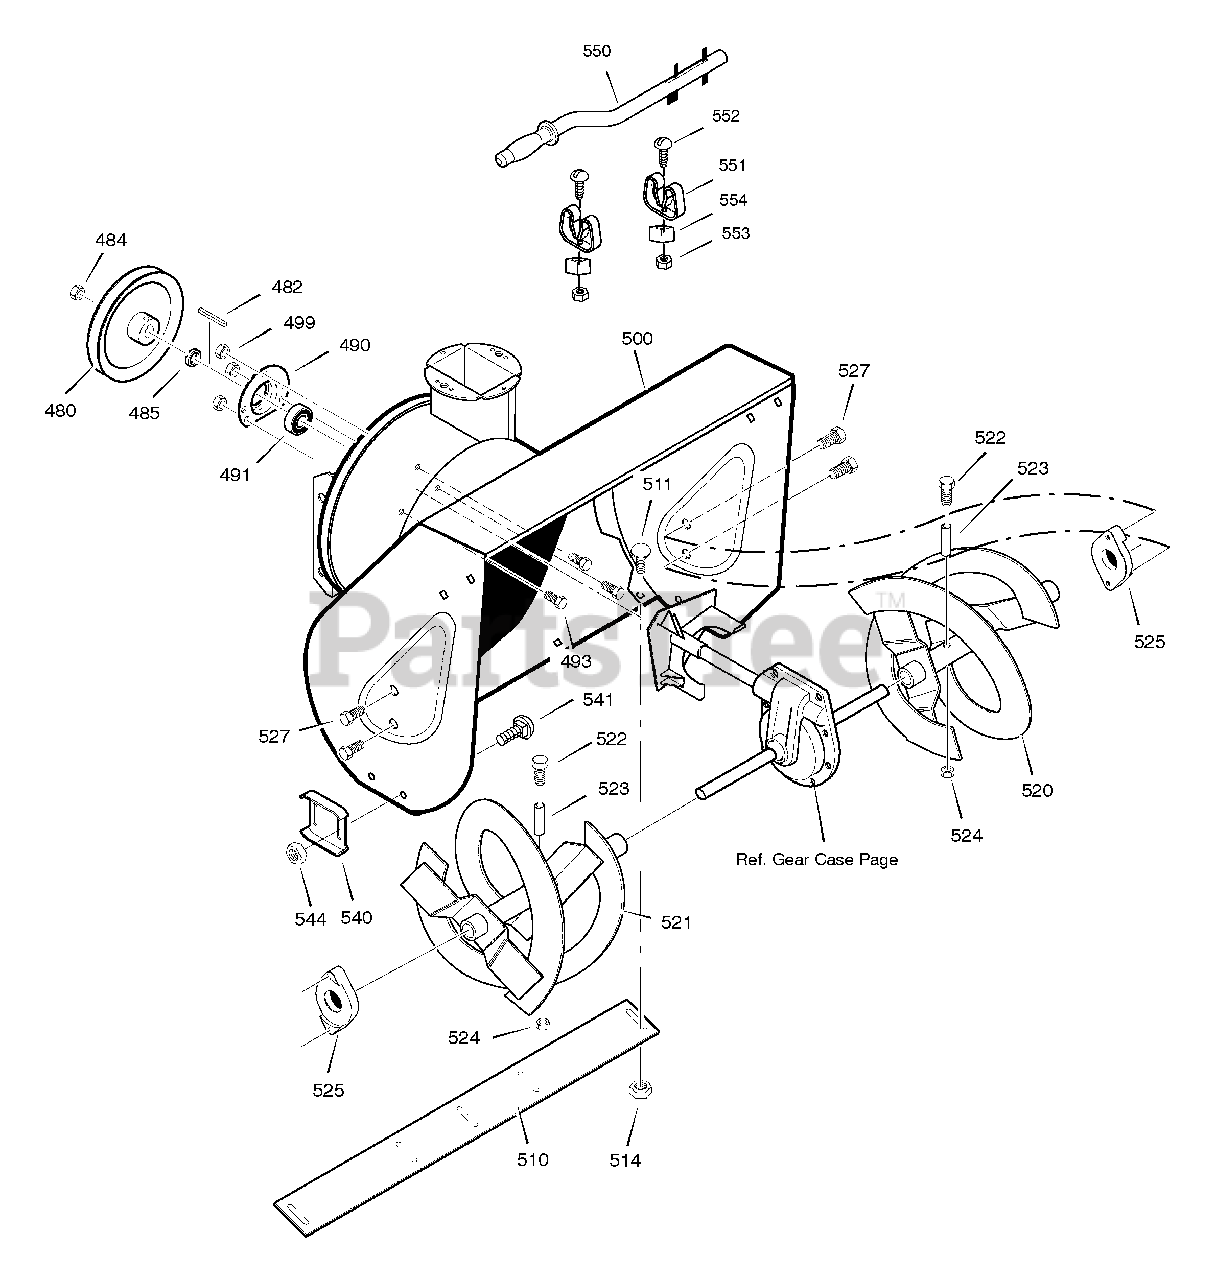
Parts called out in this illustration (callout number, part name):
480	PULLEY, 4L 8.40 OD
482	KEY, SQUARE 3/16 X 3/4
484	NUT, 1/2-20
485	SPACER, FRICTION PULLEY
490	RETAINER, BALL BRNG
491	BEARING, BALL
493	BOLT, HEX 5/16-18X .50
499	NUT, 5/16-18 HEXWDFLLK
500	HOUSING, ASSY
510	BLADE, SCRAPER
511	BOLT, 5/16-18x.62
514	NUT, 5/16-18
520	AUGER, ASSY, LH
521	AUGER, ASSY, RH
522	SCREW, 1/4-20 X 1.75
523	SPACER, SLEEVE
524	NUT, 1/4-20
525	BEARING, FLANGE
527	SCREW, 5/16-18 x 0.75
540	SKID, HEIGHT ADJUST
541	BOLT, 5/16-18 X .50
544	NUT, 5/16-18
550	BRUSH, CLEANOUT
551	CLIP, RETAINER
552	screw
553	NUT
554	BLOCK
